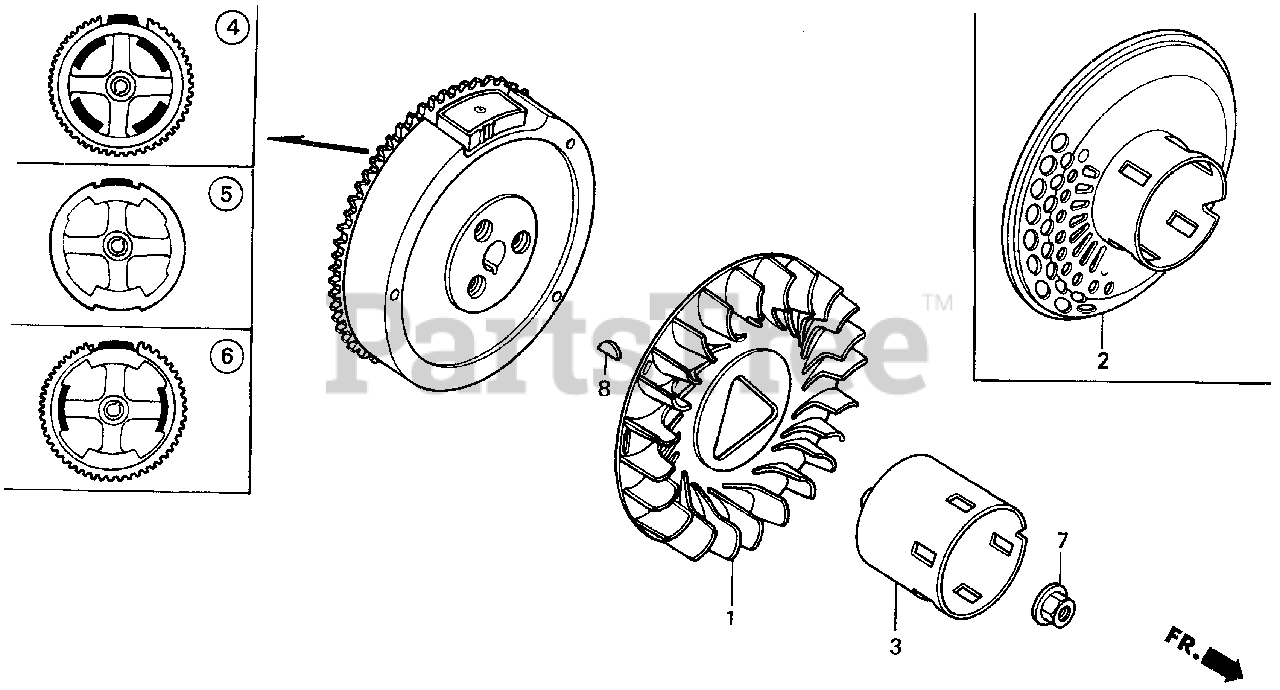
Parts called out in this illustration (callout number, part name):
1	FAN, COOLING
2	PULLEY, STARTER (SCREEN GRID)
5	FLYWHEEL
7	NUT, SPECIAL (16MM) (1)
7	NUT, SPECIAL (16MM)
8	KEY, SPECIAL WOODRUFF (25X18)
